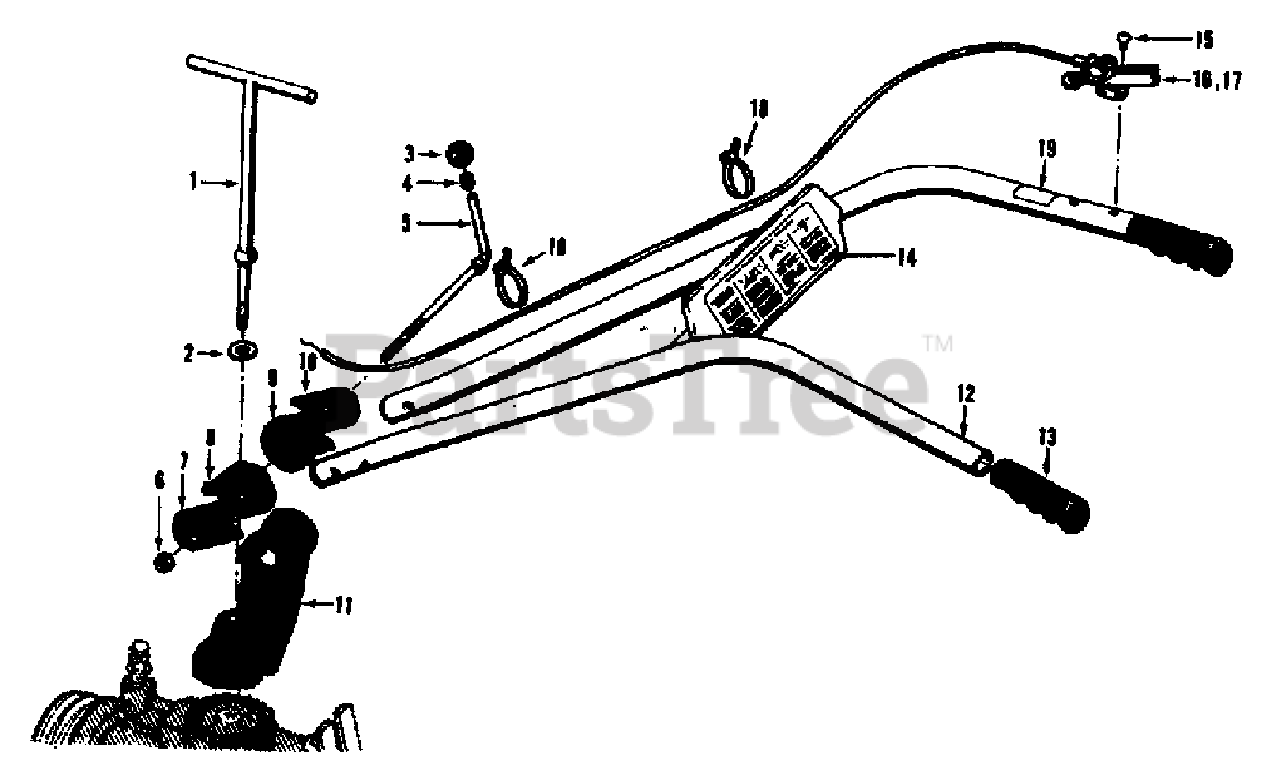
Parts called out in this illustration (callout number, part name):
1	CLAMP-T-bar, handlebar mounting
2	LOCKWASHER-spring lock 5/8"
3	KNOB -handlebar height adjustment
4	RING- retaining (tolerance ring)
5	STUD - handlebar height adjustment
6	NUT- hex., 1/2"-13
7	CLAMP- handlebar height adjustment,left
8	RATCHET- handlebar height adjustment, left
9	RATCHET- handlebar height adjustment, right
10	CLAMP - handlebar height adjustment, right
11	BASE- handlebar mounting
12	HANDLEBAR AND PANEL ASSEMBLY
13	GRIP-handlebar
14	DECAL- power unit operating instructions
15	SCREW - pan hot., #10-32 x 1/2", self-tapping
16	THROTTLE LEVER AND CABLE ASSEMBLY -
17	THROTTLE LEVER AND CABLE ASSEMBLY -
18	TIE - plastic Secures throttle cable
19	DECAL- throttle operation
